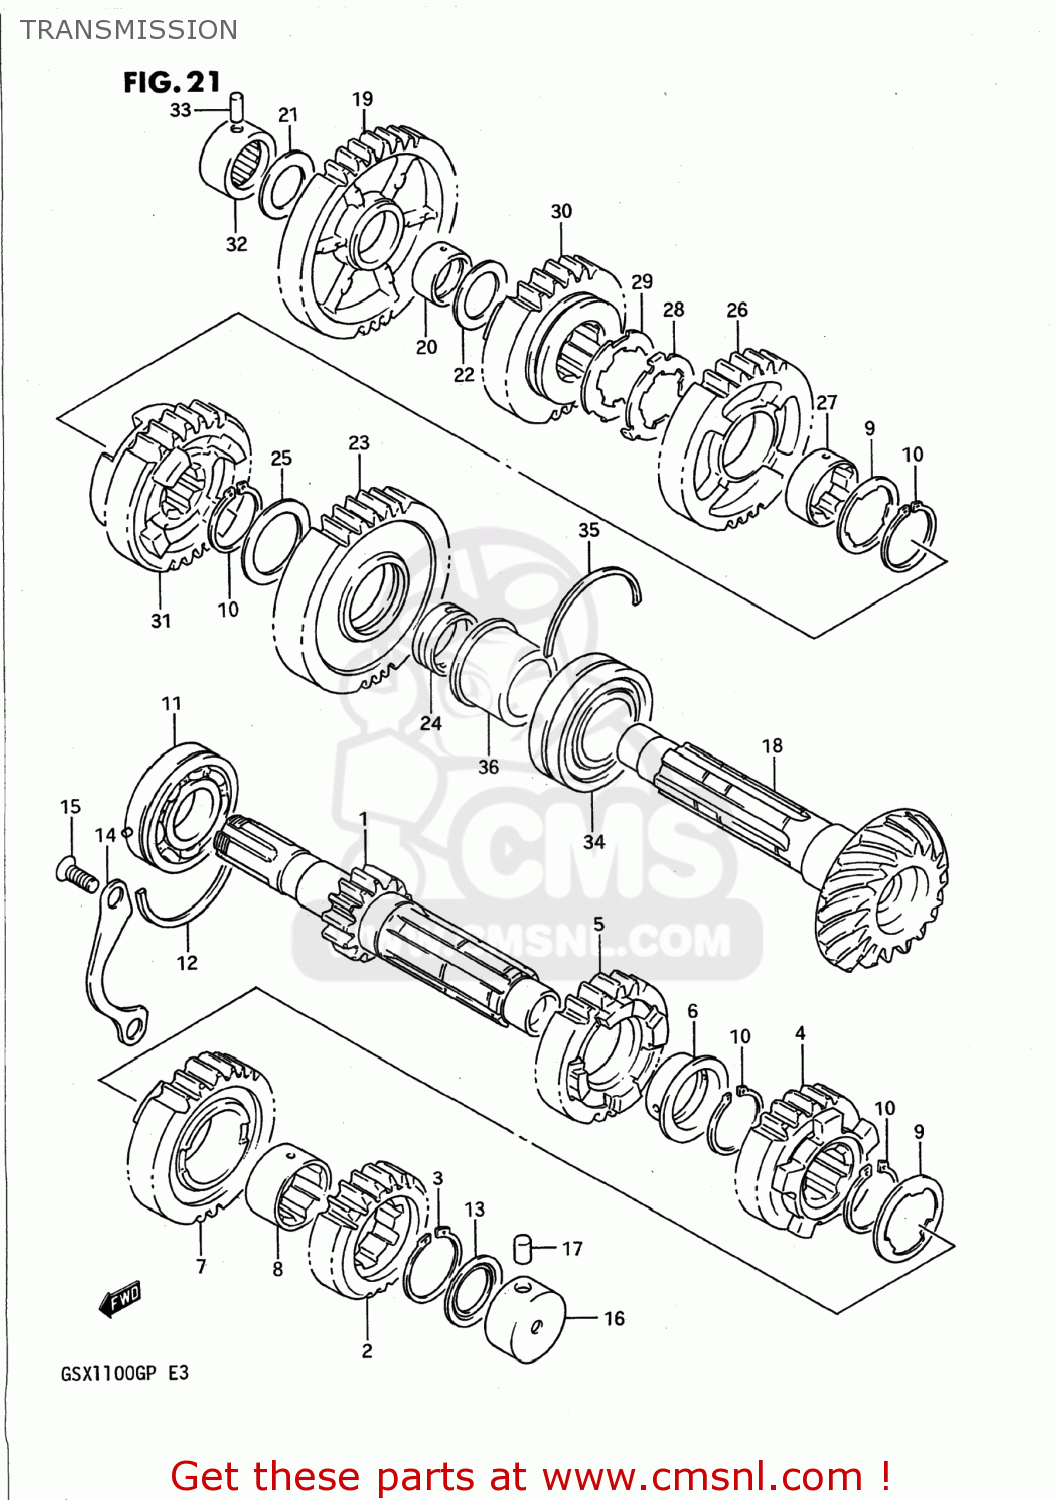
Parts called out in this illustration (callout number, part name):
1	SHAFT,COUNTER
2	GEAR,2ND DRIVE
3	CIRCLIP
4	GEAR,THIRD DRIVE
5	GEAR,4TH DRIVE
6	BUSH(28X32X2)
7	GEAR,FIFTH DRIVE
8	BUSH
9	WASHER,LOCK
10	CIRCLIP
11	BEARING(25X62X17)
12	C-RING
13	SEAL,OIL(20X31.2X2.7)
14	RETAINER,CNTR SHAFT BEARING
15	SCREW
16	BEARING(20X34X17.5)
17	PIN
18	SHAFT,DRIVE
19	GEAR,1ST DRIVEN
20	BUSHING
21	WASHER
22	WASHER
23	GEAR,2ND DRIVEN
24	BUSH(28X32X11)
25	WASHER, THRUST
26	GEAR,3RD DRIVEN
27	BUSH,3RD DRIVEN GEAR
28	WASHER,LOCK
29	WASHER,LOCK
30	GEAR,4TH DRIVEN
31	GEAR,FIFTH DRIVEN
32	BEARING(20X34X20)
33	PIN
34	BEARING(40X80X30.2)
35	C RING
36	SPACER,DRIVE SHAFT BEARING
